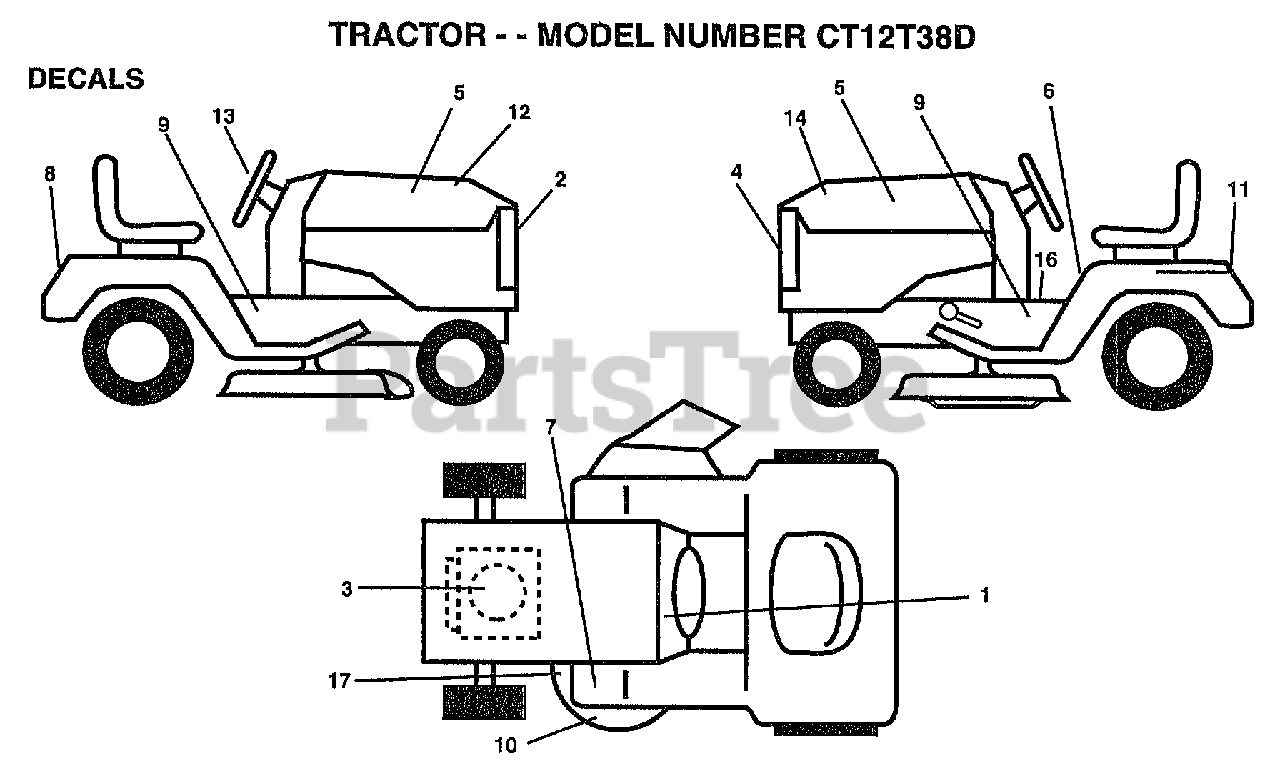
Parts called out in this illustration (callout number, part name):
1	"DECAL-OPER,GEAR D"
2	GRILL DECAL
5	DECAL.HOOD.INS.
6	"DECAL DANGER,FEND"
8	FENDER DECAL
9	DECAL CHASSIS SPEED DECK
11	DECAL.BATRY.3-3908
12	DECAL HOOD RH RLY
13	"DECAL,STR WHL"
14	DECAL HOOD LH RLY
16	DECAL BRAK PARK
17	DECAL
